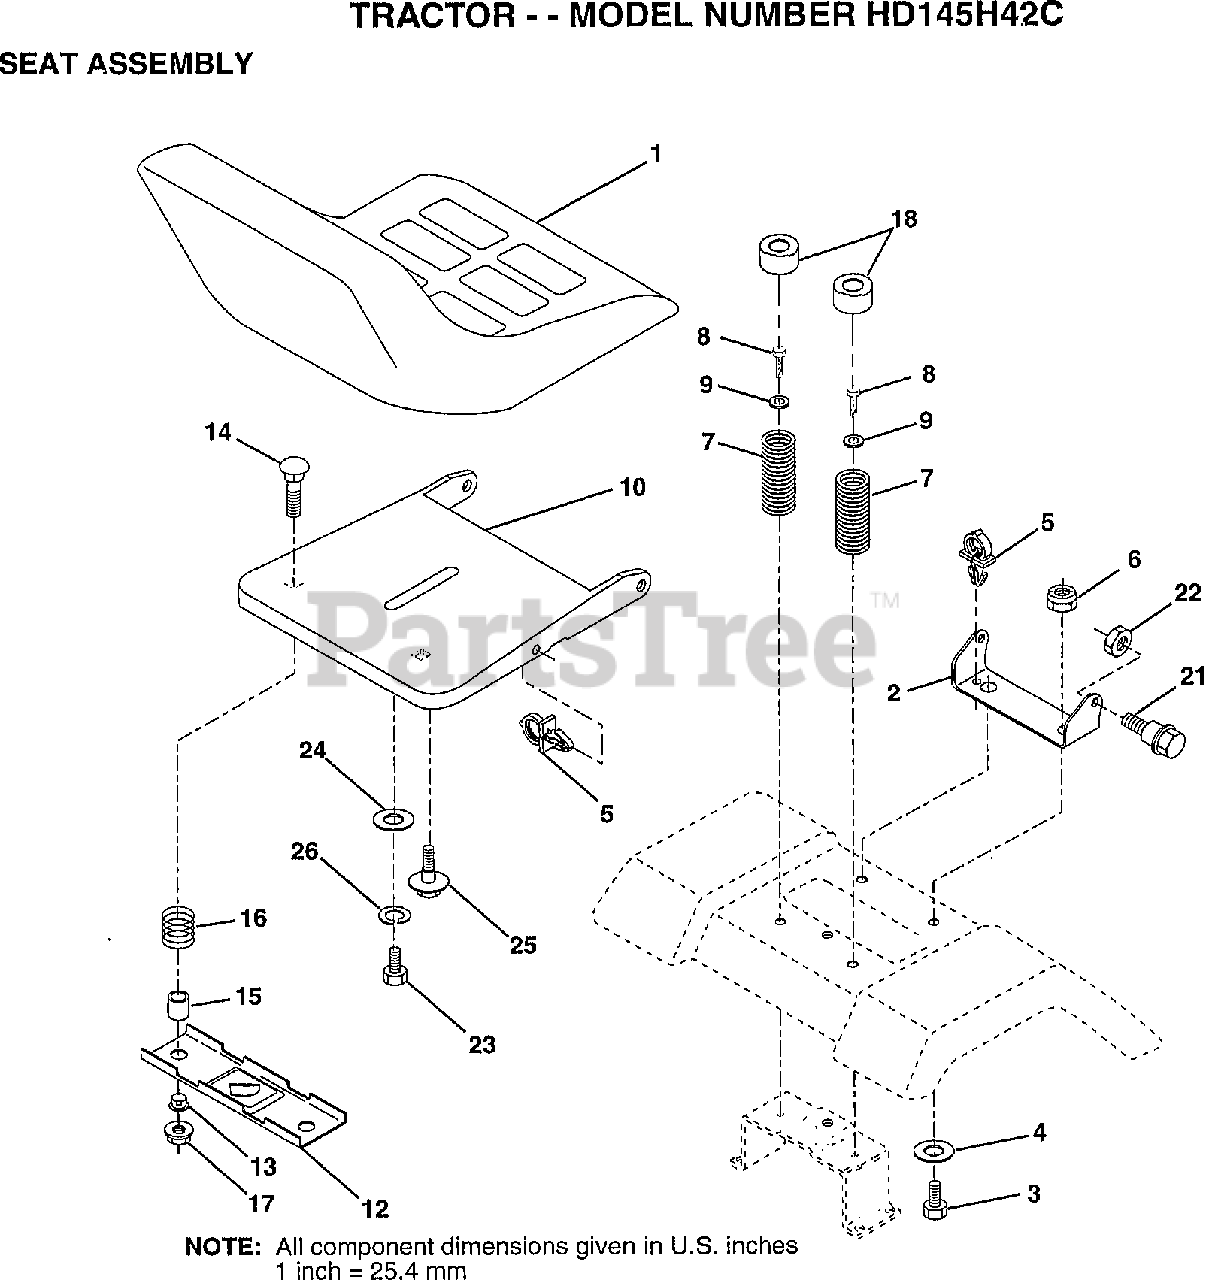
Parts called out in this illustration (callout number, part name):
1	SEAT
2	BRACKET PVT SEAT
3	BOLT
4	WASHER PM
5	CLIP.PUSH-IN.HING
6	NUT
7	SPRING COMPRESSIO
8	SCREW GTV
9	WASHER
10	PAN-SEAT
12	BRKT SWITCH
13	BUSHING
15	SPLIT SPACER
16	SPRING
18	CAP SPRING
21	"BOLT,SHOULDER"
23	BOLT
24	WASHER
25	"BOLT,SHOULDER"
26	LOCKWASHER
